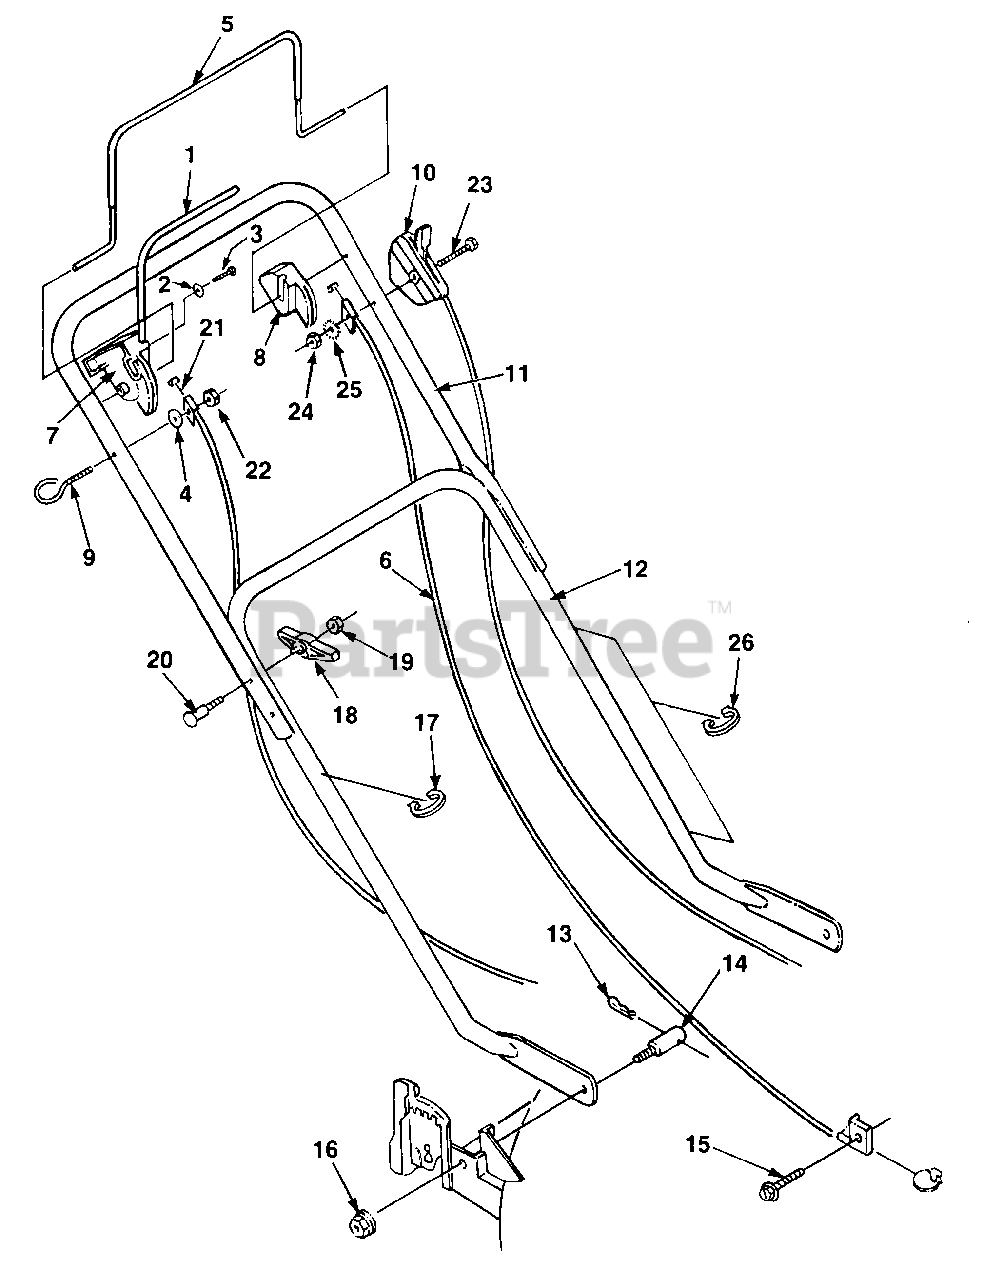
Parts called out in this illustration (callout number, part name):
1	TRACTION LEVER
3	SCREW
4	WASHER
5	BAIL- Brake control
6	CONTROL- Manual start
7	ACTUATOR- R.H.
8	ACTUATOR- L.H.
10	CONTROL- Throttle
11	HANDLE- Upper
12	HANDLE- Lower
13	PIN- Hair
16	NUT- Flanged
17	CLAMP- Cable single
18	KNOB- Handle
19	NUT- Hex
21	CABLE- Traction control
23	BOLT- Sq. neck
24	NUT- Hex
25	WASHER- External tooth
26	CLAMP- Double
